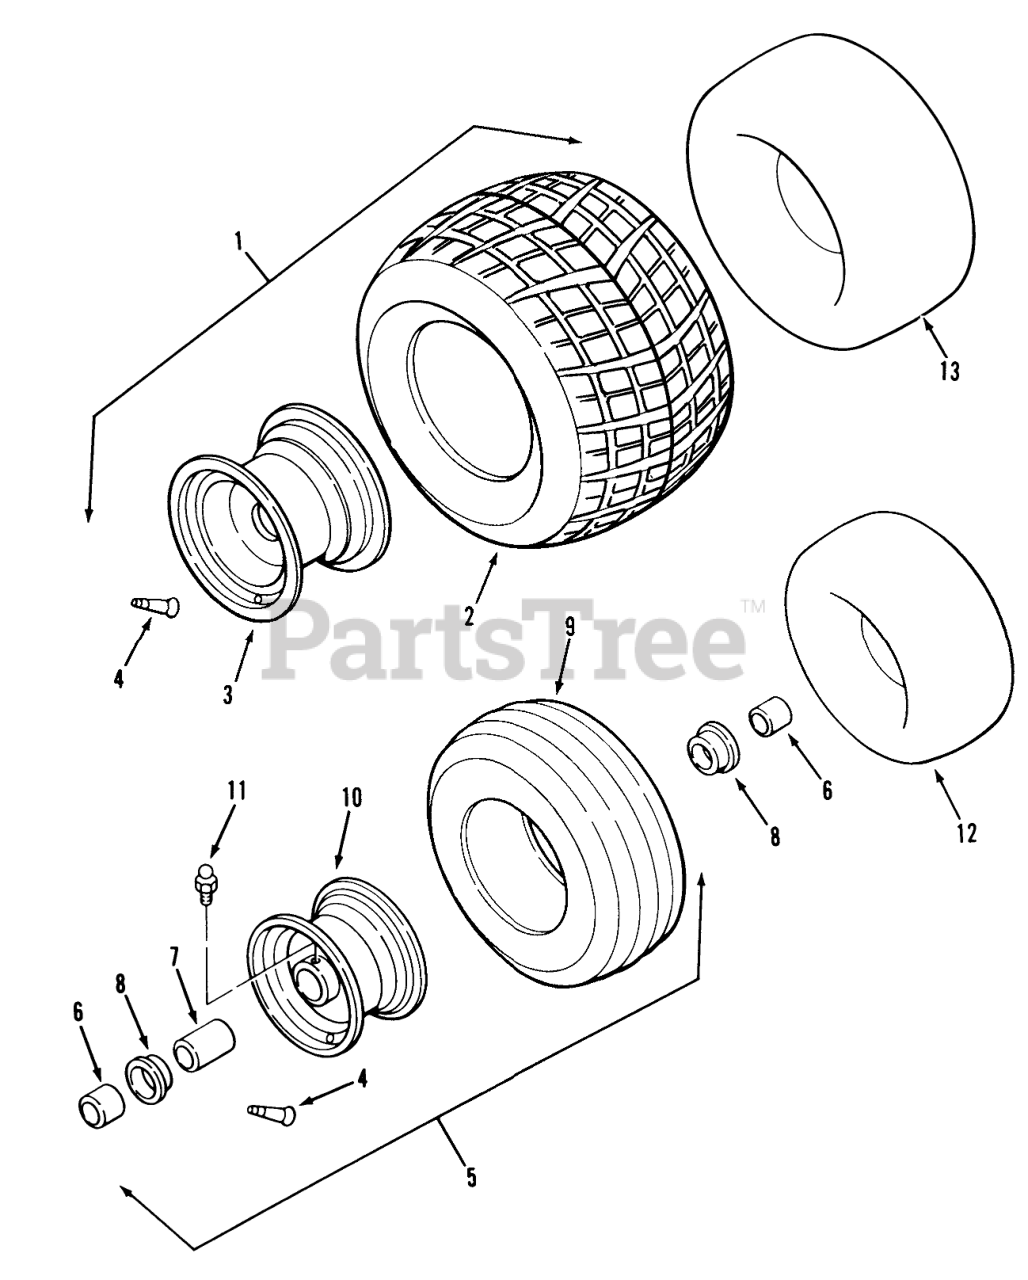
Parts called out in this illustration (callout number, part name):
2	TIRE 22 X 11.00-8
3	Wheel-Rear, Silver
4	VALVE
6	Tube-Wheel
7	SPACER FRT WHEEL INN
8	BEARING BALL
9	TIRE-FRT 13X5.00-6
10	WHEEL FT SLUV 10239K
11	Zerk
12	INNER TUBE
13	Tube-Rear
